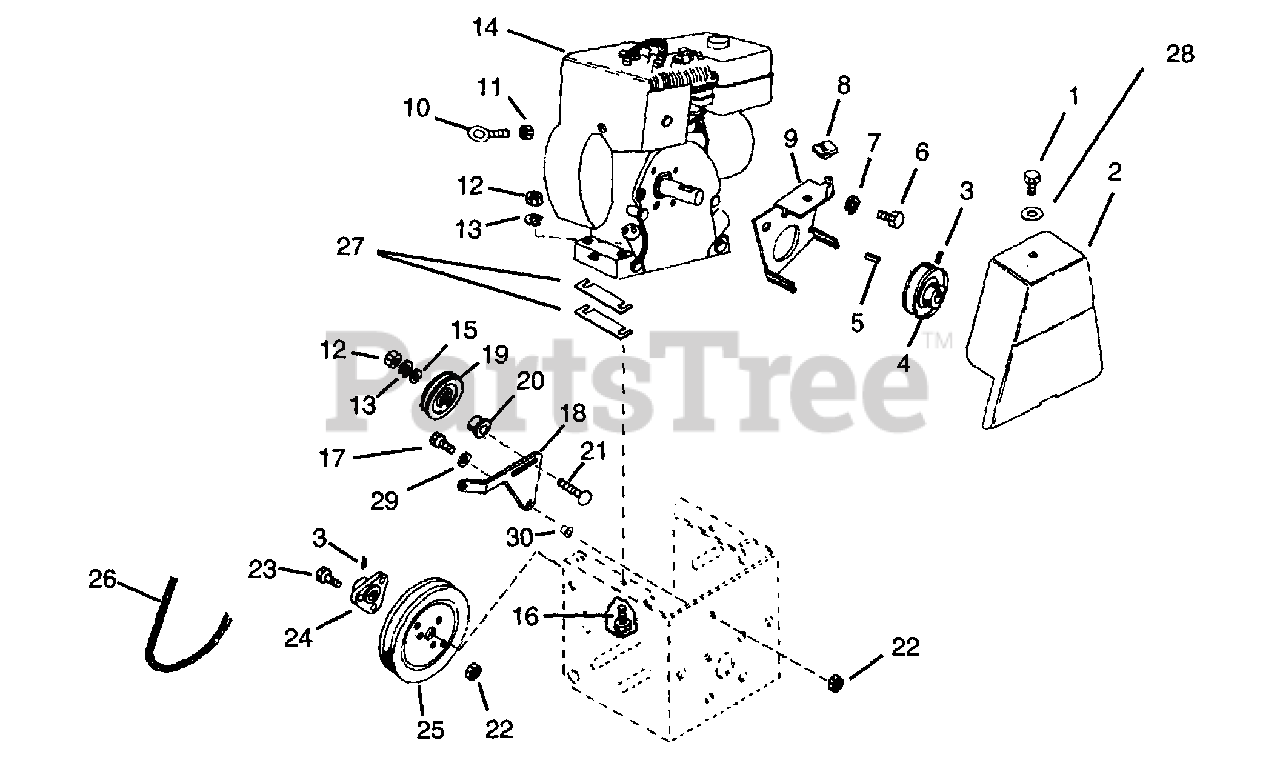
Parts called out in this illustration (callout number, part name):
1	@BLT-HEX .25-20X.50 GR5 YWZC
2	BELT COVER
3	SCR-SET .32-18X.38 SKHCUPNL OH
4	ENGINE SHEAVE
5	KEY-SQ .188X1.0X.188 SAE 8630
6	BLT-HEX .75-16X2.50 PL GR5
7	WSHR-LK .312X.097 HVY YWZC
8	NUT-SPEED U-TYPE .250-20
9	BELT FINGER COVER BRKT (TEC)
10	EYEBOLT, ROD HANGER ZC120
11	@NUT-LK-CTR .25-20 YWZC
12	@NUT-HEX .31-18 YWZC
13	WSHR-LK .312X.097 HVY YWZC
14	ENGINE TECUMSEH 3.5HPCHORE HR
15	@WSHR-FL-STL.38X.875X.083 YWZC
16	@BLT-HEX .31-18X1.75 GR5 YWZC
17	@BLT-HEX .31-18X.75 GR5 YWZC
18	ARM, IDLER
19	IDLER
20	SPCR, BRG .315X.50X.688X.281
21	@BLT-RDHDSQNK .31-18X1.50 G5YZ
22	@NUT-LK-CTR .31-18 YWZC
23	BLT-SERRDHD SL .31-18X.75 YZ
24	HUB
26	V-BELT, 4L-RAW EDGE
27	SHIM YWZC
28	@WSHR-FL-STL.250X.56X.049 YWZC
29	WSHR-FL-STL .344X1.375X.075YWZ
30	BSHG-FLG .325X.465X.350X.685
